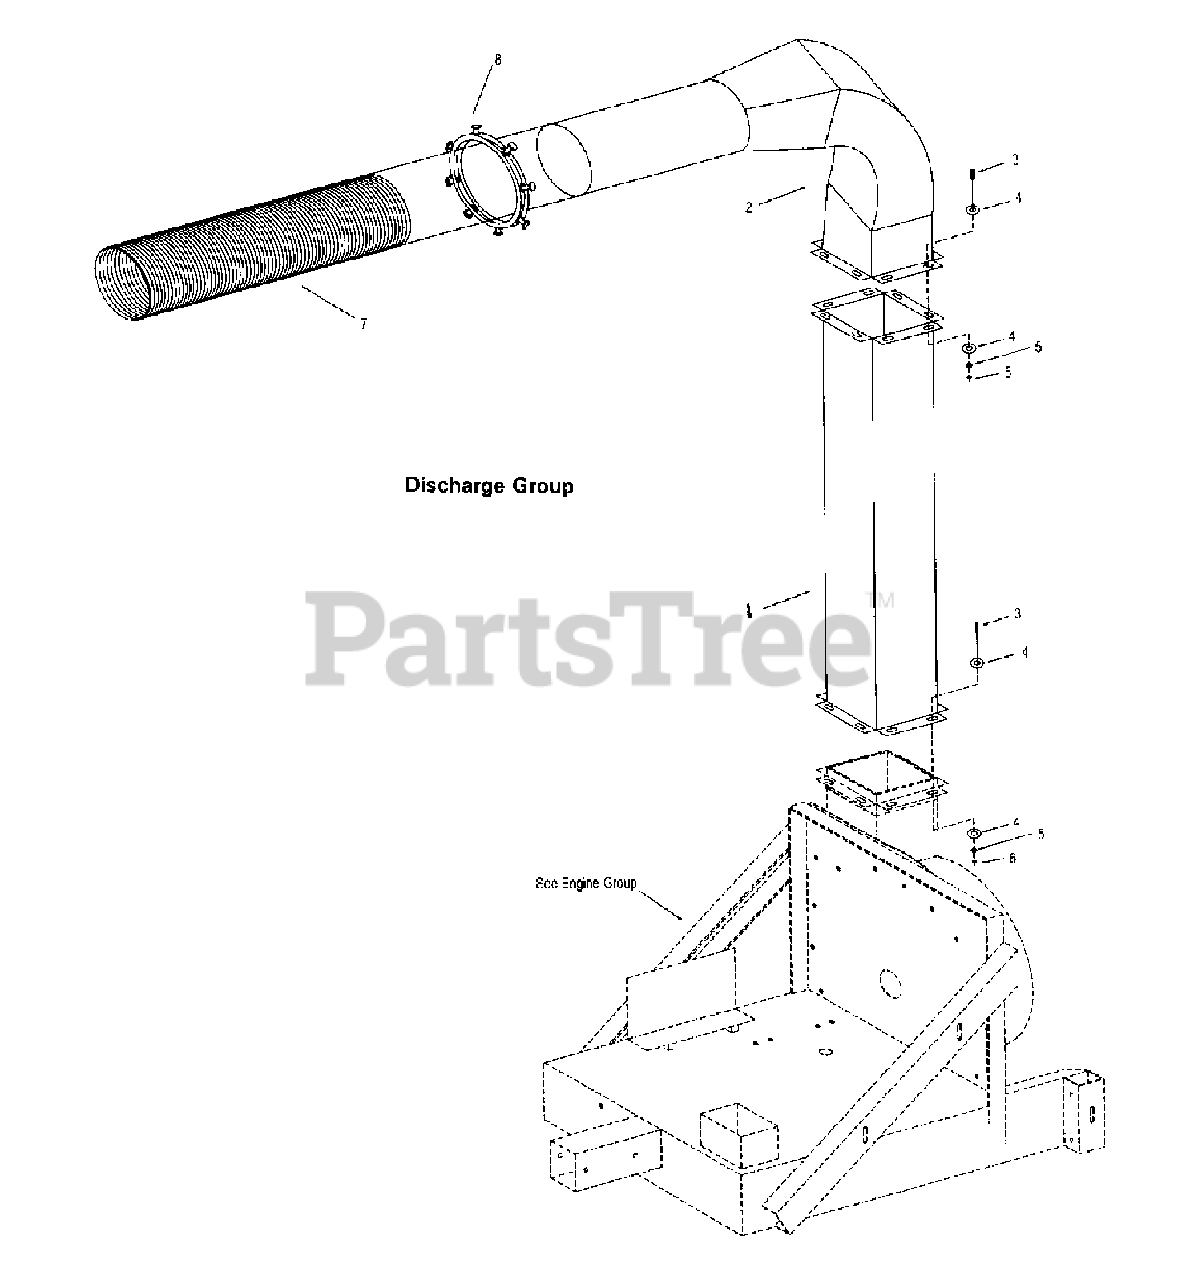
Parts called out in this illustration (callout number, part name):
1	Discharge Stack
2	Discharge Elbow (No Off Set)
3	3/8-16 x 1-1/4 Hex Bolt
4	3/8 Flat Washer
5	3/8 Lock Washer
6	3/8-16 Hex Nut
7	Hose, Discharge 8" x 5' Metal
8	Ring, Squeeze 8"
